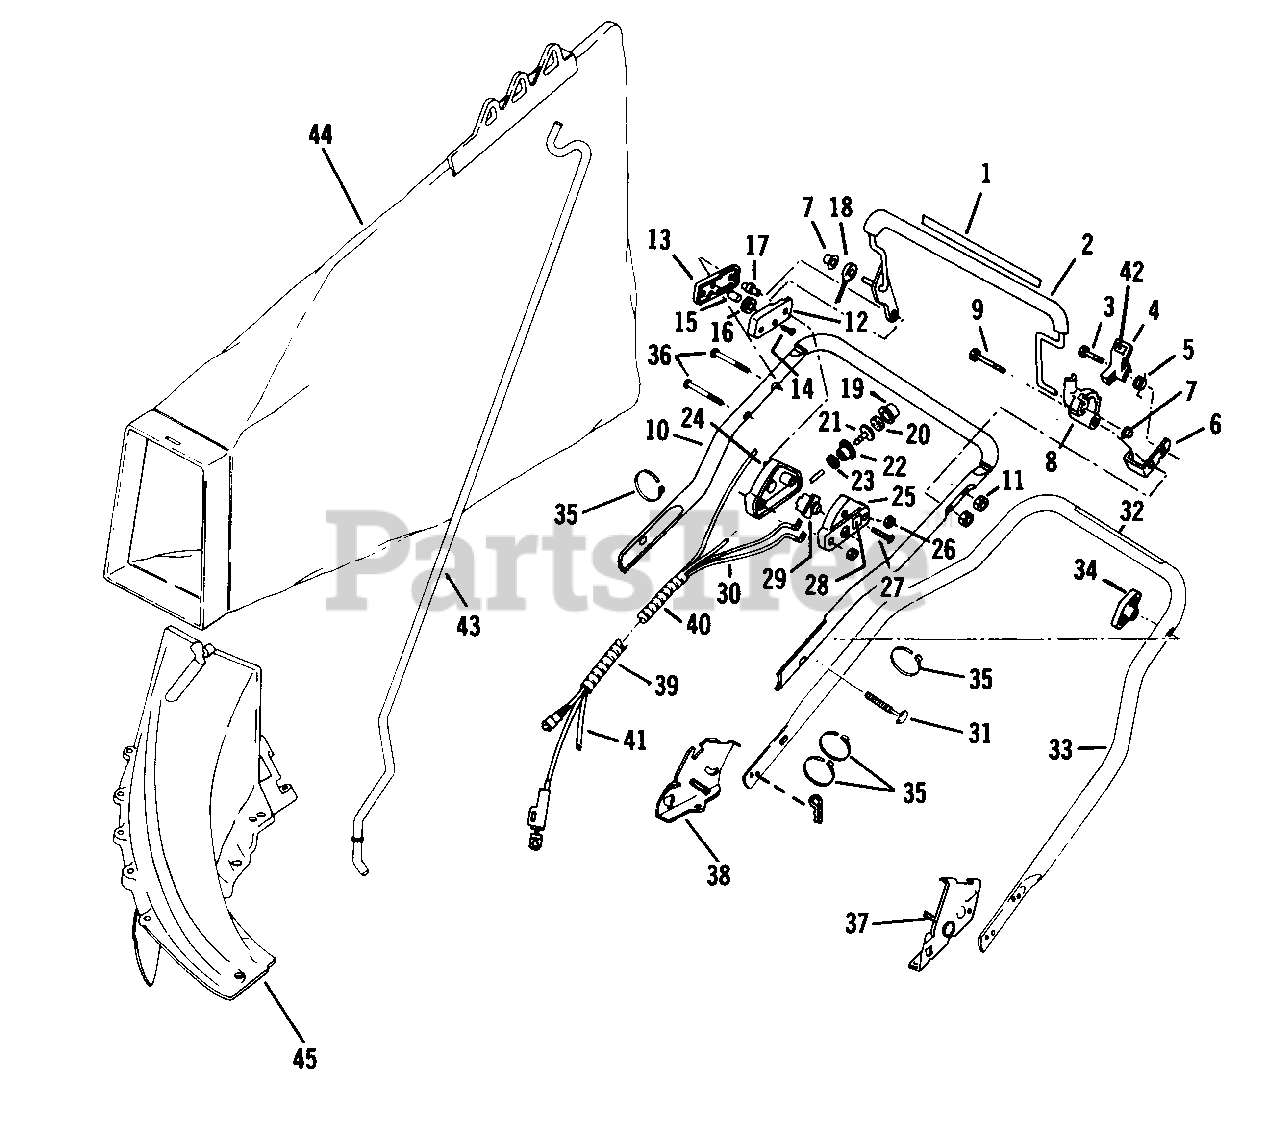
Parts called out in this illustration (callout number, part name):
1	Decal-Blade Control
2	Control Lever Assembly
3	Shoulder Bolt-Latch Lever Mounting
4	Stop-Latch Lever
5	Spring-Torsion
6	Bracket-Bail Stop
7	Push Nut
8	Cam-Clutch Control
9	Shoulder Bolt-Cam Mounting
10	Top Handle and Grip Assembly
11	Lock Nut
12	Control Case-Inner
13	Control Case-Outer
14	Screw-Truss Head
16	Pulley
18	Control Cable Assembly
19	Primer Bulb
21	Primer Base
23	Locknut
24	Console Right
25	Console Left
26	Locknut-Hex
27	Screw-Truss Head
28	Decal-"OFF-ON"
29	Switch Assembly
30	Wire Harness Assembly
31	Screw-Folding Handle
32	Decal-Starting Inst.
33	Handle-Bottom
34	Knob-Folding Handle
35	Tie Strap
37	Handle Bracket-L.H.
38	Handle Bracket-R.H.
39	Spiral Tubing
40	Spiral Tubing
41	Tubing-Primer
42	Decal-Latch Lever
43	Rod-Grass Bag
44	Bag Assembly
45	Chute Assembly
46	Hair Pin
